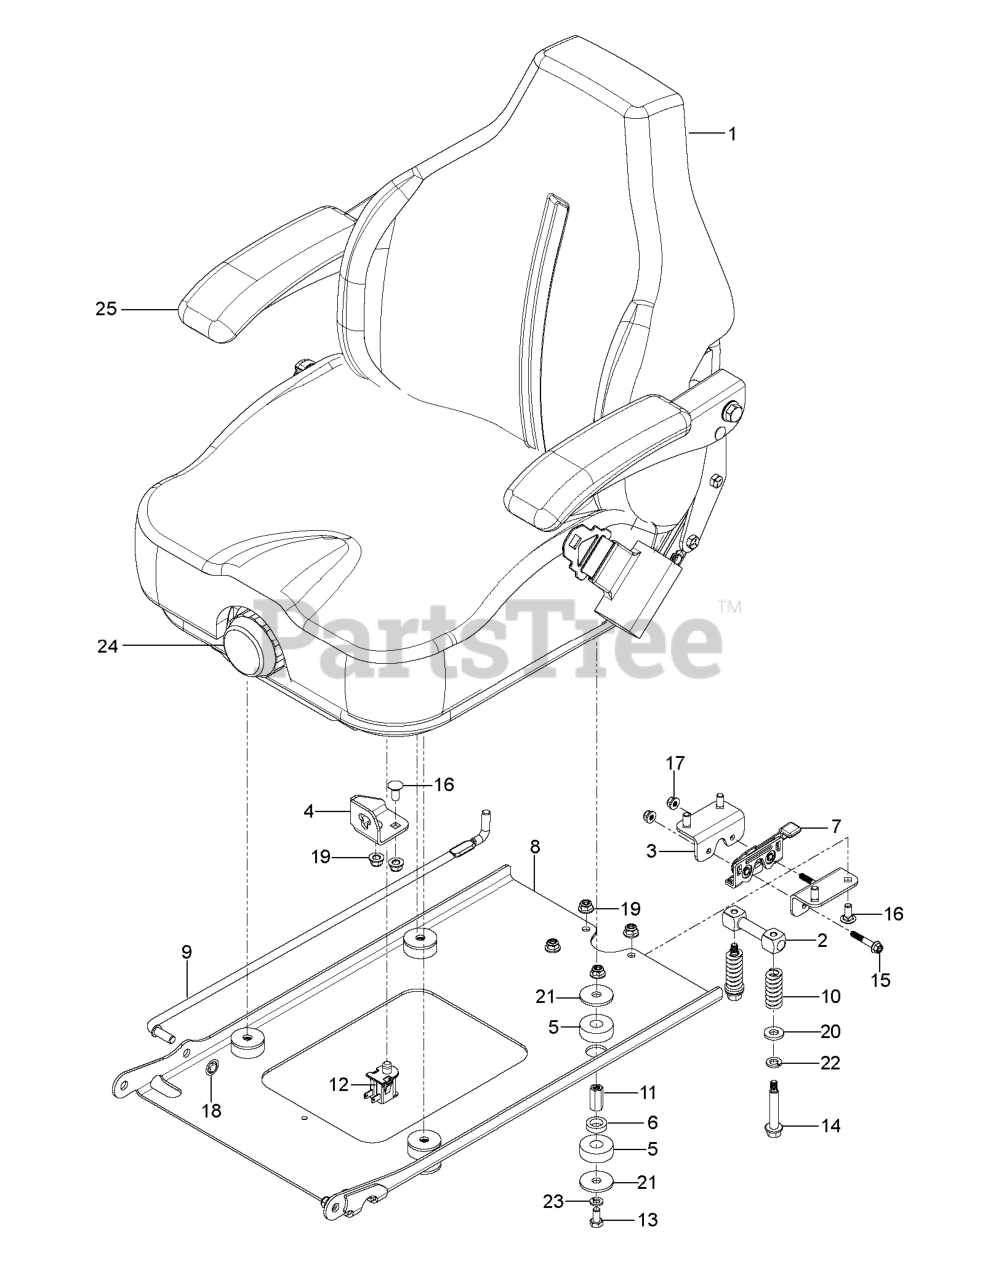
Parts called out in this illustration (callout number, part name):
1	SUSPENSION SEAT
1	SEAT
2	BAR.LATCH.SEAT
3	BRACKET.MTG.LATCH
4	BRACKET.SEAT.STAY.ROD
6	ISO-MOUNT INSERT
7	LATCH.ROTARY
8	PLATE.PNT.MTG.SEAT.EDIP
9	ROD.SEAT.STAY
11	NUT.HEX.COUPLING.5/16-18X1-1/8
12	SWITCH.SEAT.DP W/RAMPS
13	HCS 5/16-18 X 5/8 GR 5 ZD
14	SCREW.SHLDER.3/8" DIA X 2.5/16
15	SCREW.HHFS.1/4-20X1.5".GR8.ZY
16	BOLT 5/16C X 3/4" CARRIAGE
17	NUT.FLG.NYLOCK.1/4-20.GR.G.ZY
18	NUT 3/8 PALNUT RTNG BLK PHOS
19	5/16-18 NYLOC FLANGE NUT
20	WASHER, 3/8 THICK
21	WASHER.13/32 X 1 X 1/2.11GUARD
22	SLW 3/8 STD
23	WASHER.LOCK.HVY.HLCL.SPR.5/16
24	Suspension
25	Arms
